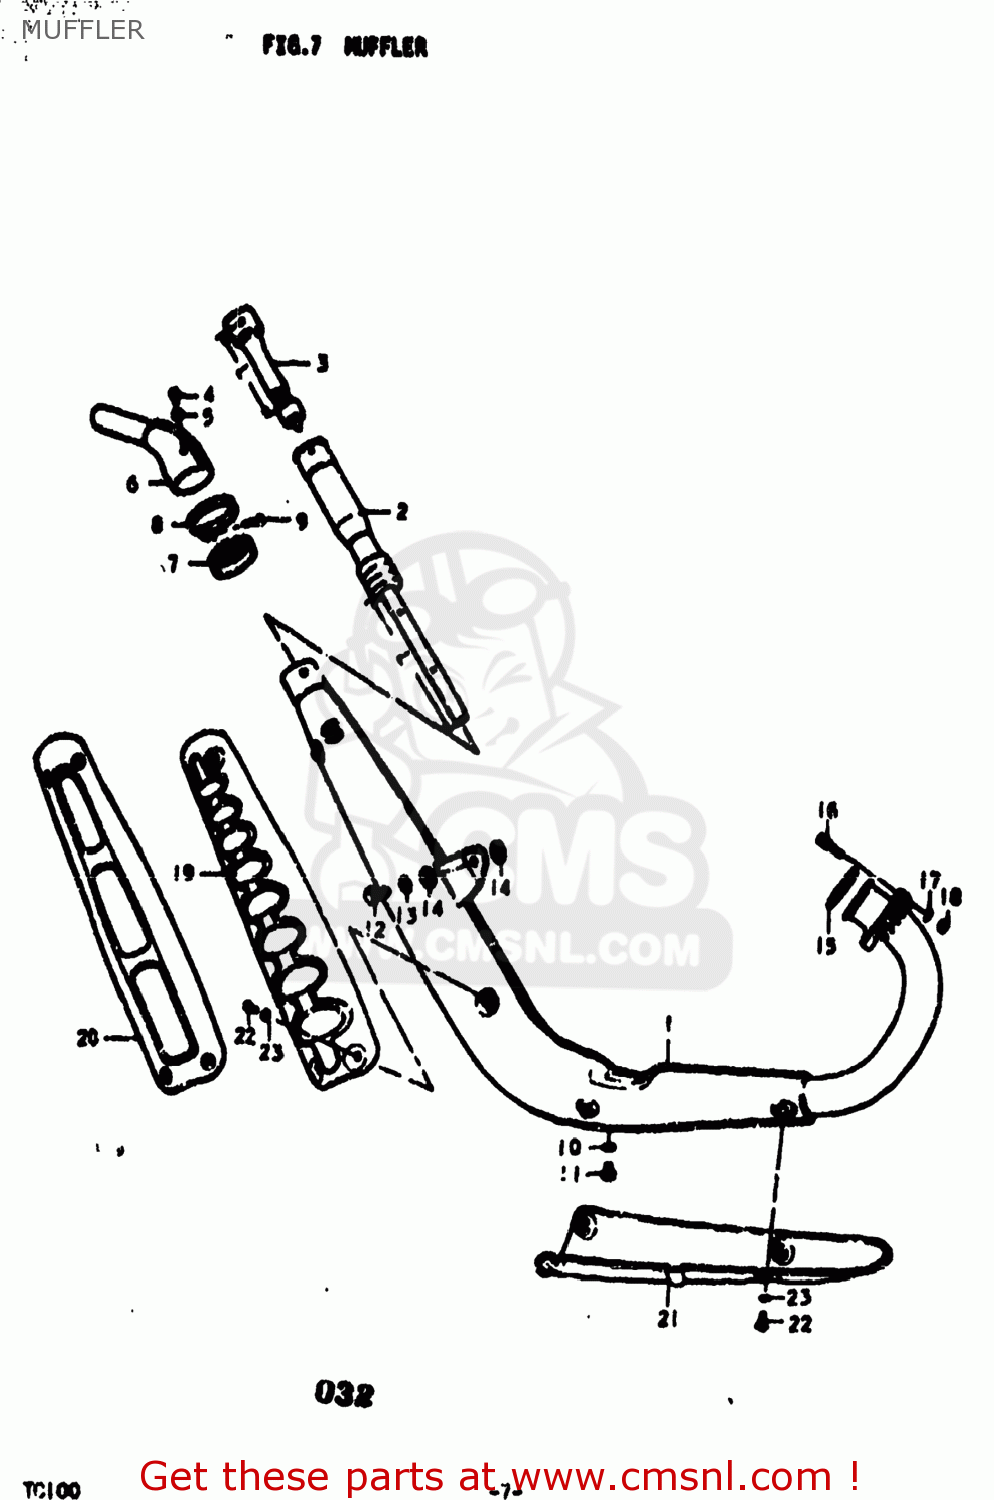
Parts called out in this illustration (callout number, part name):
1	MUFFLER ASSEMBLY
2	ARRESTER,SPARK
3	TUBE,MUFFLER CLEAN OUT
4	SCREW 6X12
5	GASKET
6	EXHAUST EXTENSION
7	GASKET,MUFFLER TAIL PIPE (NAS)
8	CLAMP
9	SCREW
10	GASKET(10X14X3.6) (NAS)
11	BOLT 10X9
12	BOLT
13	LOCK WASHER
14	WASHER
15	GASKET,EXHAUST PIPE (NAS)
16	STUD
17	LOCK WASHER
18	NUT
19	COVER,MUFFLER
20	COVER,MUFFLER
21	COVER,MUFFLER
22	SCREW
23	LOCK WASHER
